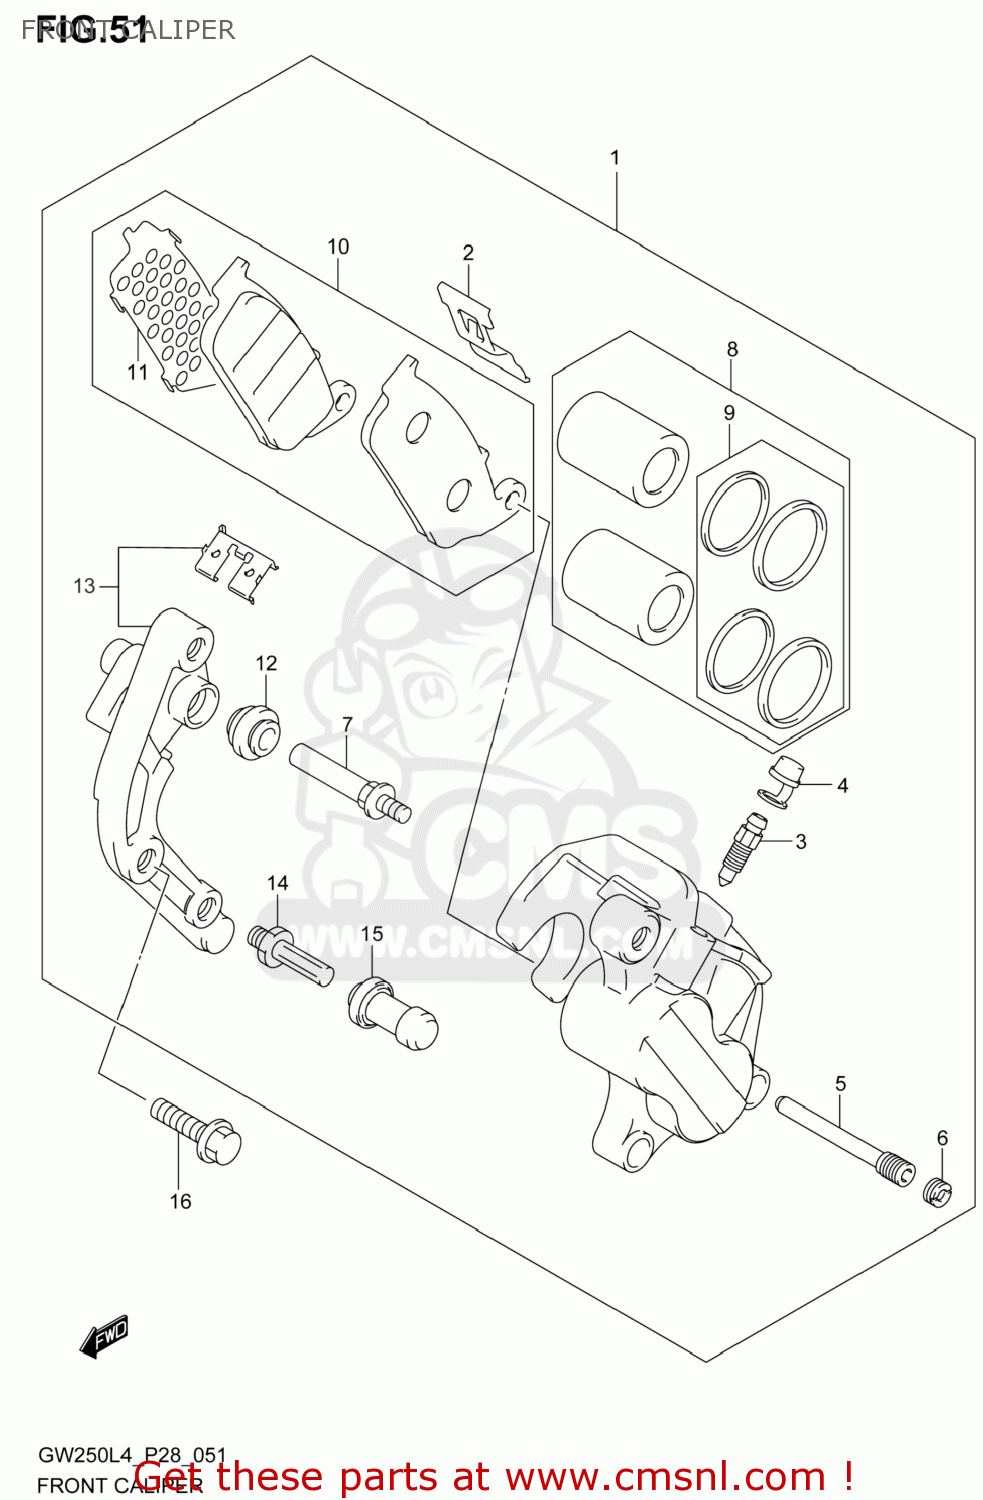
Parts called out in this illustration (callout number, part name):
1	CALIPER ASSY,FR,L
2	SPRING,PAD
3	BLEEDER
4	CAP,BLEEDER
5	PIN,HANGER
6	PLUG,PIN
7	PIN
8	PISTON SET
9	SEAL SET,PISTON
10	PAD SET (NAS)
11	SHIM,PAD
12	BOOT
13	BRACKET
14	PIN,BOLT
15	BOOT
16	BOLT
